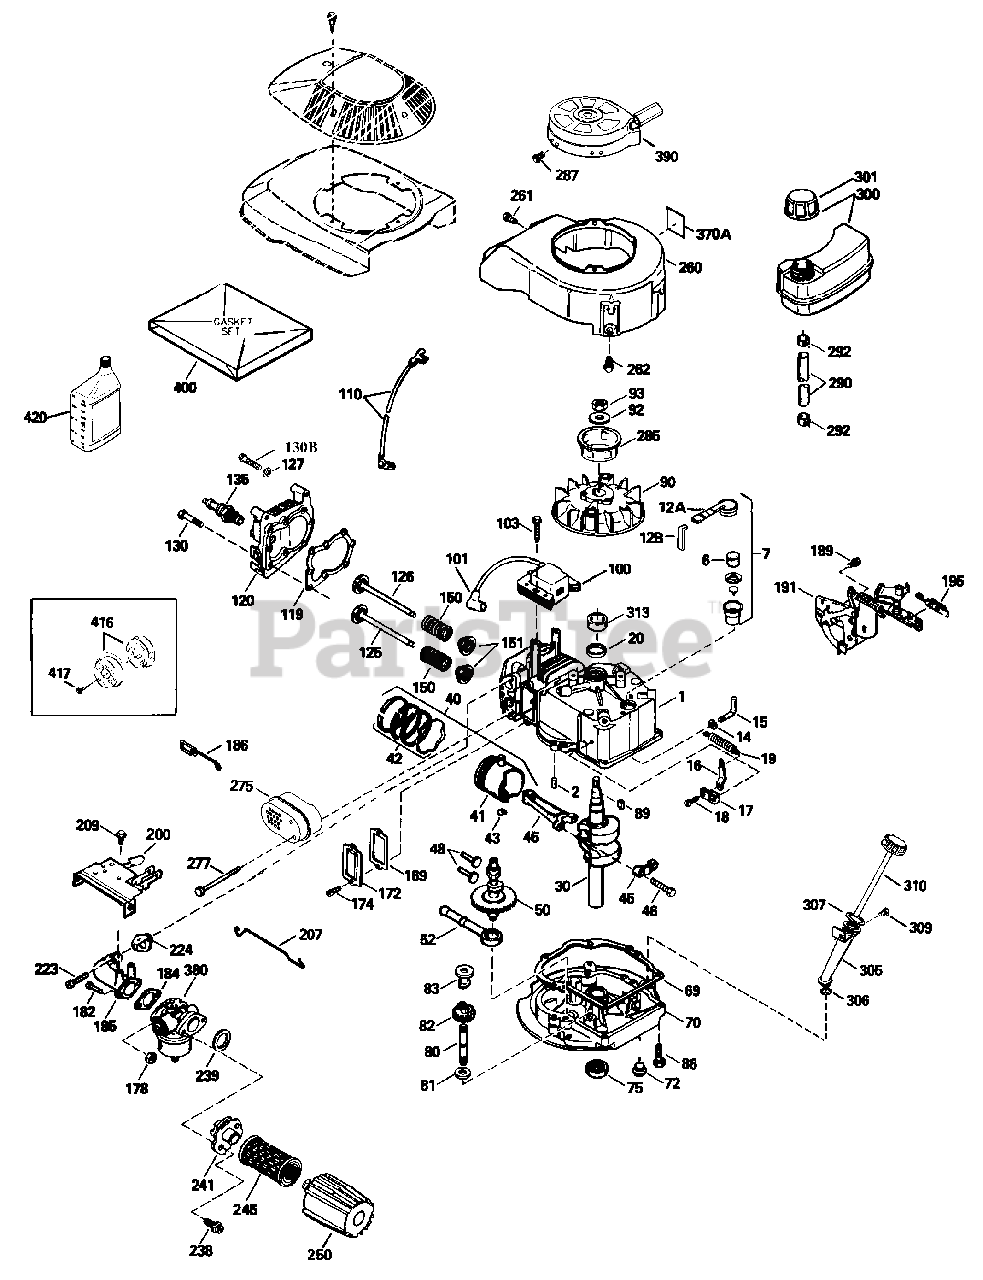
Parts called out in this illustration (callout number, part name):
1	Cylinder (Incl. 2, 7, 20 & 125)
2	Dowel Pin
6	Breather Element
7	Breather Body Ass'y. (Incl. 6 & 12A)
12A	Breather Cover & Tube (Incl. 12B)
12B	Breather Tube Elbow
15	Governor Rod
16	Governor Lever
17	Governor Lever Clamp
19	Extension Spring
20	Oil Seal
30	Crankshaft
40	Piston, Pin & Ring Set (Std.)
40	Piston, Pin & Ring Set (.010" OS)
40	Piston, Pin & Ring Set (.020" OS)
41	Piston & Pin Ass'y. (Std.)(Incl. 43)
41	Piston & Pin Ass'y. (.010" OS)
41	Piston & Pin Ass'y. (.020" OS)
42	Ring Set (Std.)
42	Ring Set (.010" OS)
42	Ring Set (.020" OS)
43	Piston Pin Retaining Ring
45	Connecting Rod (Incl. 46)
46	Connecting Rod Bolt
48	Valve Lifter
50	Camshaft (MCR)
52	Oil Pump Ass'y.
69	Mounting Flange Gasket
70	Mounting Flange (Incl. 72 thru 83)
72	Oil Drain Plug
75	Oil Seal
80	Governor Shaft
82	Governor Gear Ass'y. (Incl. 81)
83	Governor Spool
89	Flywheel Key
90	Flywheel
92	Belleville Washer
93	Flywheel Nut
100	Solid State Ignition
101	Spark Plug Cover
103	Screw, Torx T-15
110	Ground Wire
119	Cylinder Head Gasket
120	Cylinder Head
125	Exhaust Valve (Std.)(Incl. 151)
125	Exhaust Valve (1/32" OS)(Incl. 151)
126	Intake Valve (Std.)(Incl. 151)
126	Intake Valve (1/32" OS)(Incl. 151)
135	Resistor Spark Plug (RJ19LM)
150	Valve Spring
151	Valve Spring Cap
169	Valve Cover Gasket
172	Valve Cover
178	Nut & Lock Washer
182	Screw
184	Carburetor To Intake Pipe Gasket
185	Intake Pipe
186	Governor Link
191	S.E. Brake Bracket (Incl. 195)
195	Terminal
200	Control Bracket
207	Throttle Link
224	Intake Pipe Gasket
239	Air Cleaner Gasket
241	Air Cleaner Collar
245	Air Cleaner Filter
250	Air Cleaner Cover
260	Blower Housing
275	Muffler (Incl. 277)
285	Starter Cup
290	Fuel Line
292	Fuel Line Clamp
300	Fuel Tank (Incl. 292 & 301)
301	Fuel Cap
305	Oil Fill Tube
306	"O"-Ring
307	"O"-Ring
309	Screw, 10-32 x 7/16"
310	Dipstick
370A	Lubrication Decal
380	Carburetor (Incl. 184)
390	Rewind Starter (NOTE: This engine could have been built with 590739 starter. Refer to the design of the rope pulley strength ribs for part identification. Individual starter parts do not interchange. Refer to service bulletin 116.)
400	Gasket Set (Incl. Items Marked PK in Notes) Incl. part #'s: 26756 (1), 27234A (1), 33735 (1), 34265 (1), 34338 (1), 36477 (1), 34690A (1), 35261 (1),
416	Spark Arrestor Kit (Incl. 417)(Optional)
417	Screw (Optional)
420	SAE 30 4-Cycle Engine Oil (Quart)
